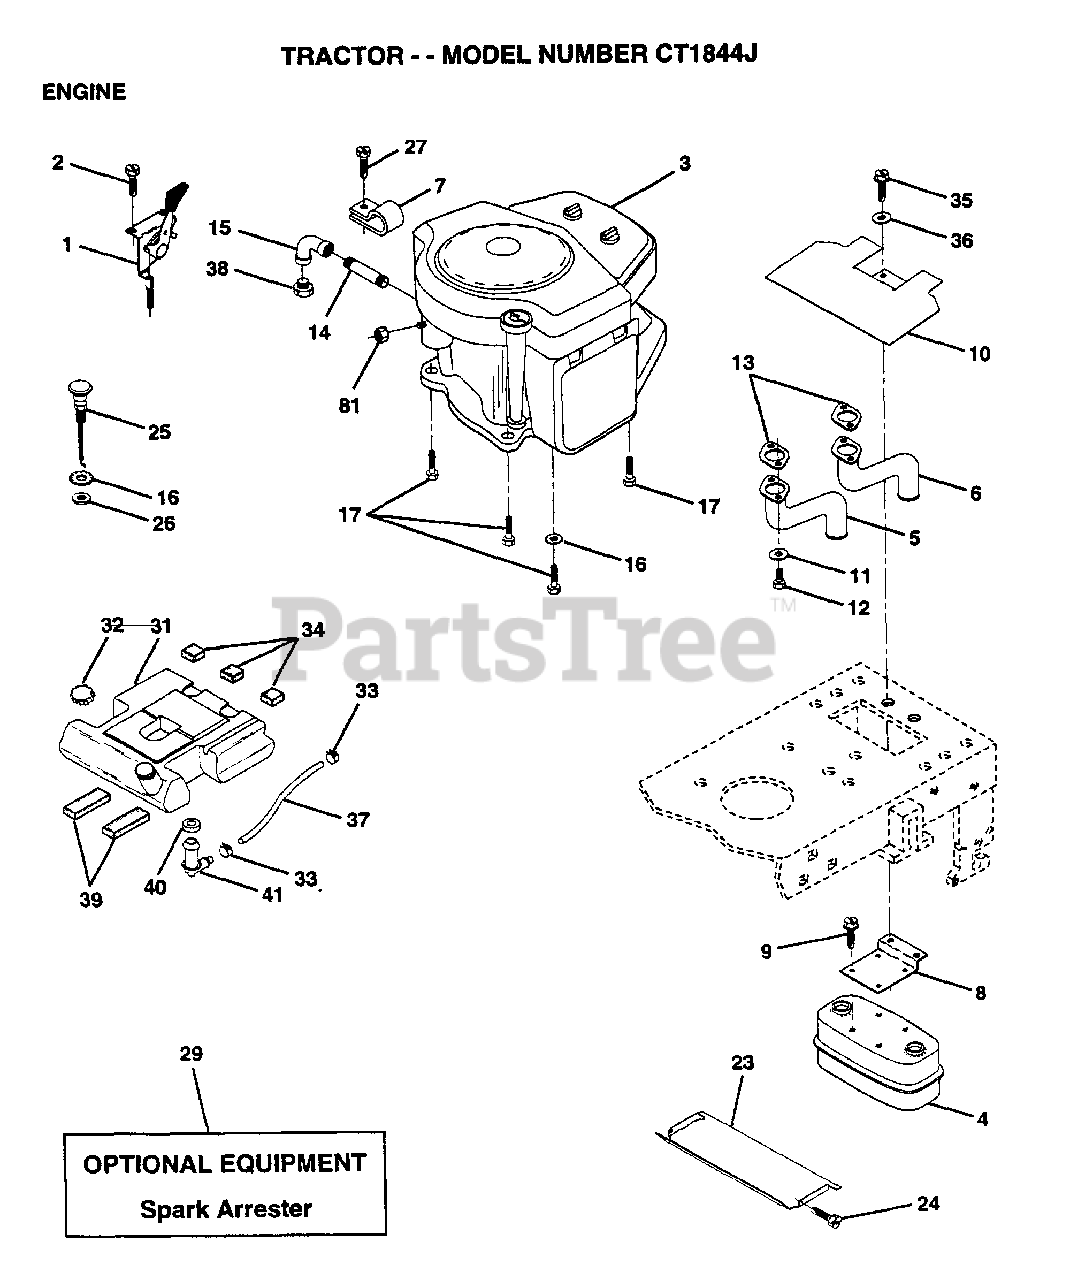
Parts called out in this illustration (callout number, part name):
2	SCREW LT
5	EXHAUST.B&S.18.LH
6	EXHAUST.B&S.18.RH
7	CLAMP.TUBE.DBL.EN
8	BRACKET MUFFLER
9	SCREW ST
10	SHIELD.HEAT.
11	LOCKWASHER
14	PIPE NIPPLE LT
15	ELBOW
16	LOCKWASHER
17	SCREW LT
23	HEAT SHIELD
24	SCREW
25	"CONTROL.CHOKE.51"""
27	SCREW.10-24X1/2
32	CAP ASM FUEL
33	HOSE CLAMP
34	PAD-SPACER LT
35	SCREW
36	WASHER
37	FUEL LINE T
39	PAD IDLER TI
40	BUSHING OUTLET T
41	STEM.TANK.FUEL
81	NUT
